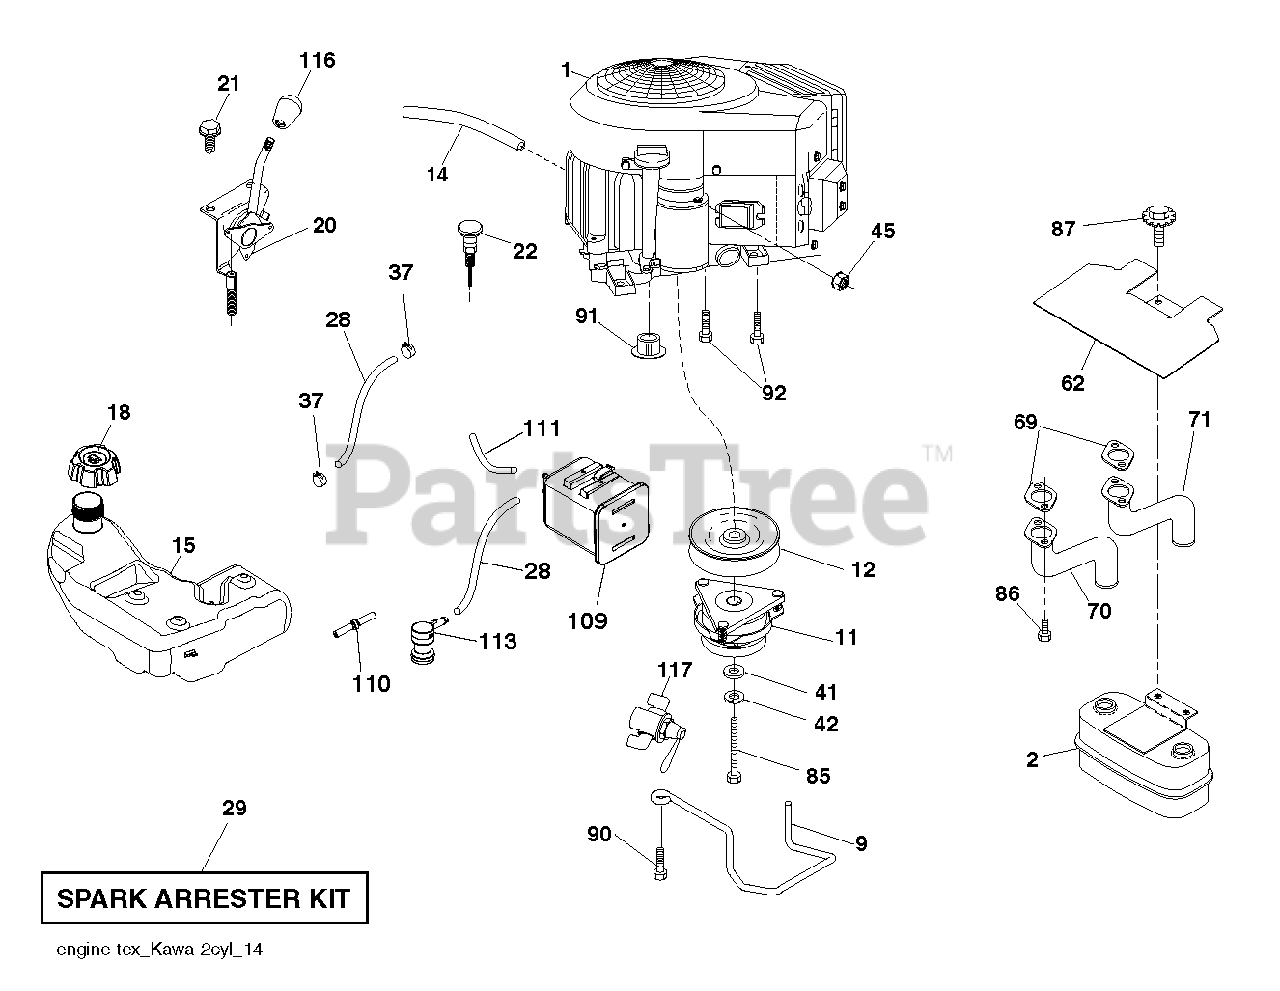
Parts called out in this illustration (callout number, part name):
1	Husqvarna TBD
2	MUFFLER.TWIN.CYL.LOW.TONE
9	KEEPER.BELT.ENGINE.4.2
11	CLUTCH.ELECTRIC.LT.48"*
12	PULLEY.ENGINE.TUFFTORQ
14	TUBE, DRAIN OIL ASM.
15	TANK.ASM.4.GAL.CARB.2.PORT.REA
18	CAP.ASM.FL.RITCH.3"E10.SYM.498
20	CONTROL.THROTTLE.PRO.
21	SCREW.#10 X 0.750.BOS
22	CONTROL.CHOKE.ERGO.PUSH-IN.BLA
28	LINE.FUEL.64"REAR.EMIS
29	KIT.SPARK ARRESTOR 794945 B&S
37	HOSE CLAMP
42	LOCKWASHER
45	NUT
62	SHIELD.HEAT.MUFFLER
70	TUBE.EXHAUST.LH.FR961/FR730
71	TUBE.EXHAUST.RH.FR961/FR730
85	BOLT HEX 7/16-20X4-1/4"
86	NUT.HEX.FLANGE.TOPLOCK
87	Bolt, 5/16-18 X 1-3/4
90	SCREW 3/8-16X1
91	BUSHING.1.375OD
92	SCREW 3/8-16X1
109	CANNISTER, CARBON
110	VALVE.ASM.ANTI-SLOSH
111	PURGE.LINE.36"REAR.CALIFORNIA
113	VALVE.SLANT.CARTRDG.90 DEG.TEX
116	KNOB - SHIFT
117	VALVE FUEL RESERVE
